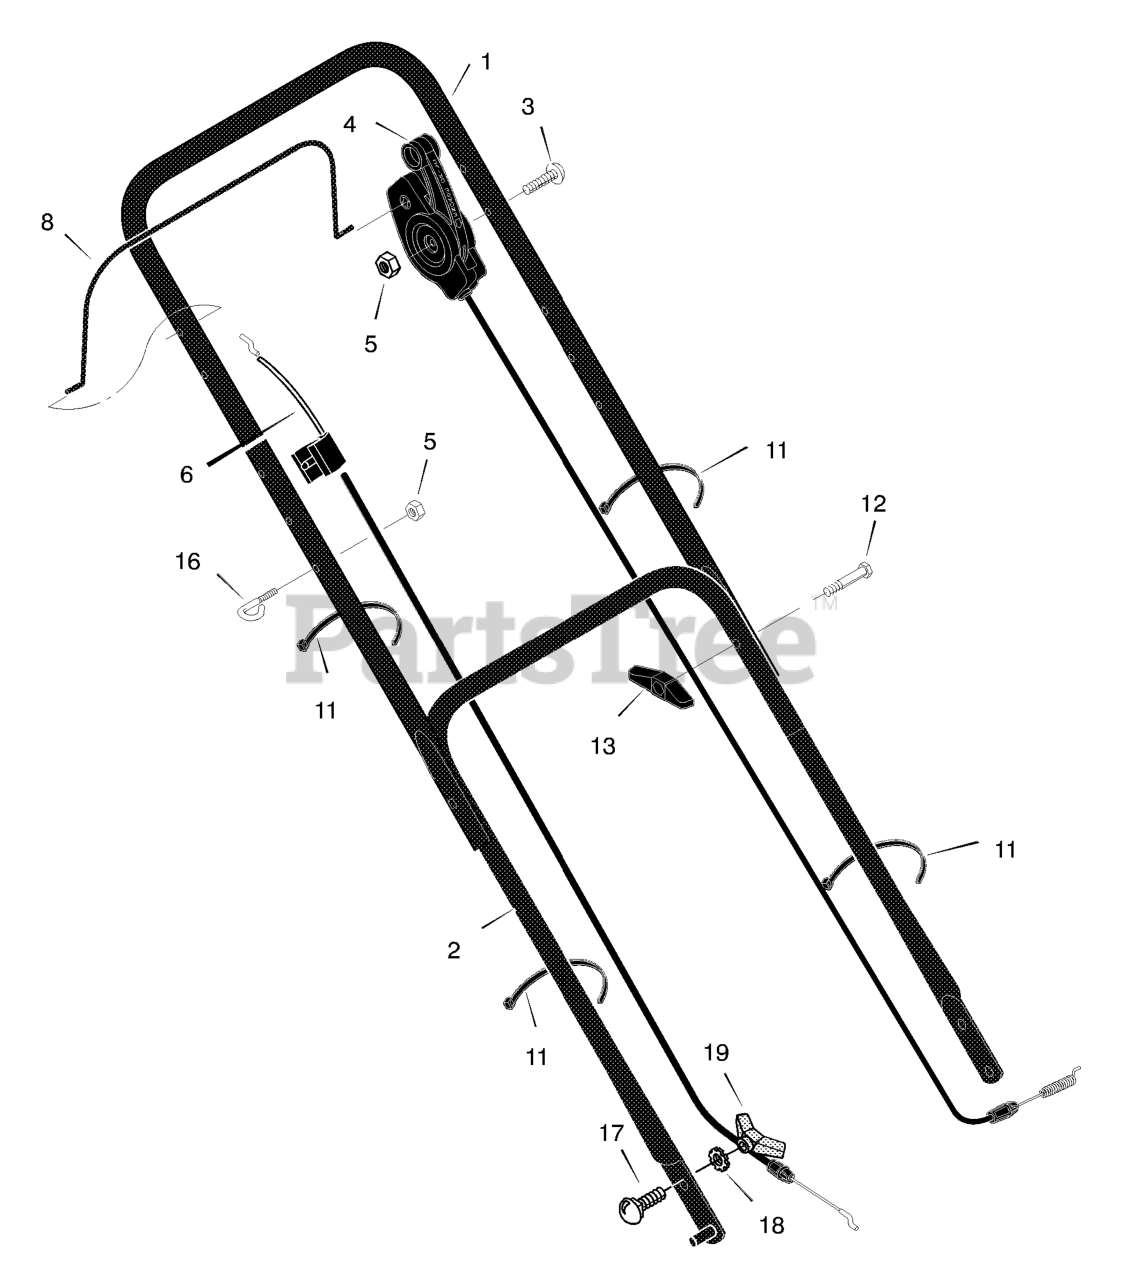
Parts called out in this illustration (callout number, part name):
1	Handle, Upper
2	Handle, Lower
4	Control, Drive
5	Locknut
6	Cable, Stop
8	Engine Stop Lever
11	Fastener, Cable
13	Knob
16	Guide, Rope
17	Bolt, Carriage
18	Washer
19	Knob, Plastic
